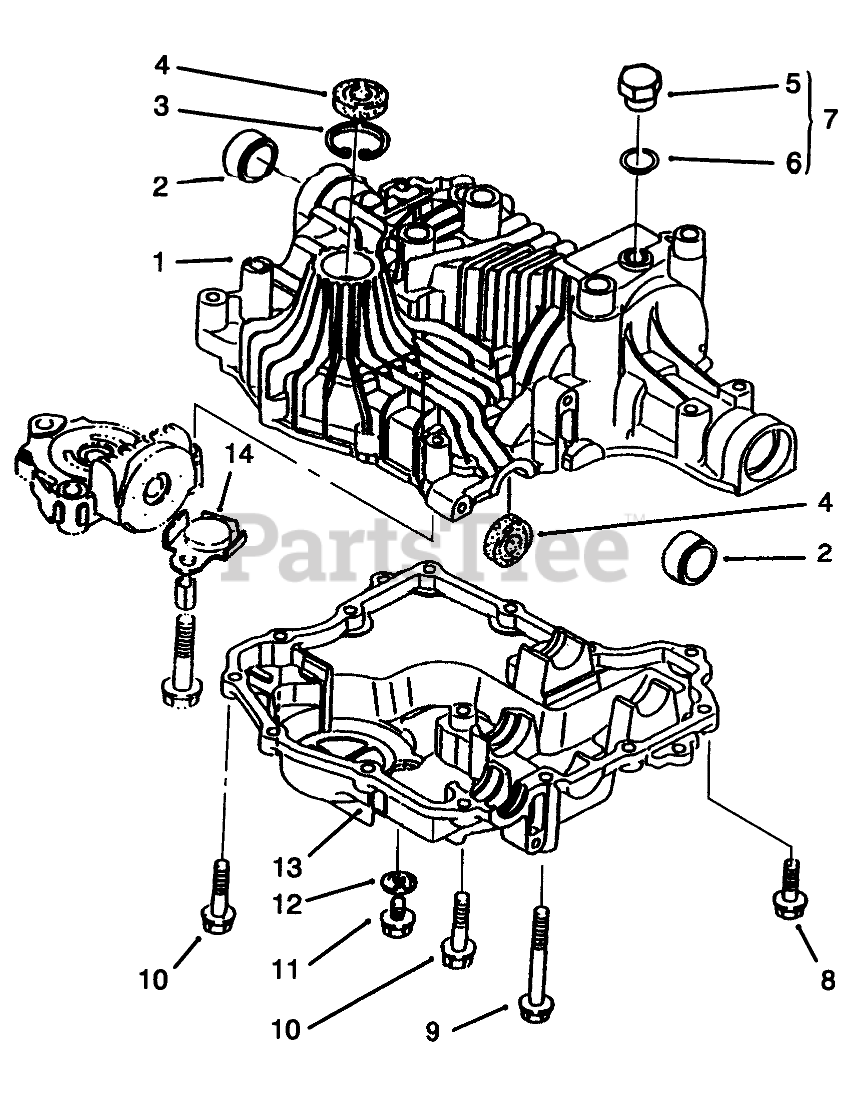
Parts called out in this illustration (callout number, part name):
1	ASM - UPPER CASE
3	RING
4	SEAL
5	Plug
6	Packing
7	PLUG-PACKING
8	SCREW-TAP
10	SCREW-TAP
13	CASE - LOWER
14	MAGNET
